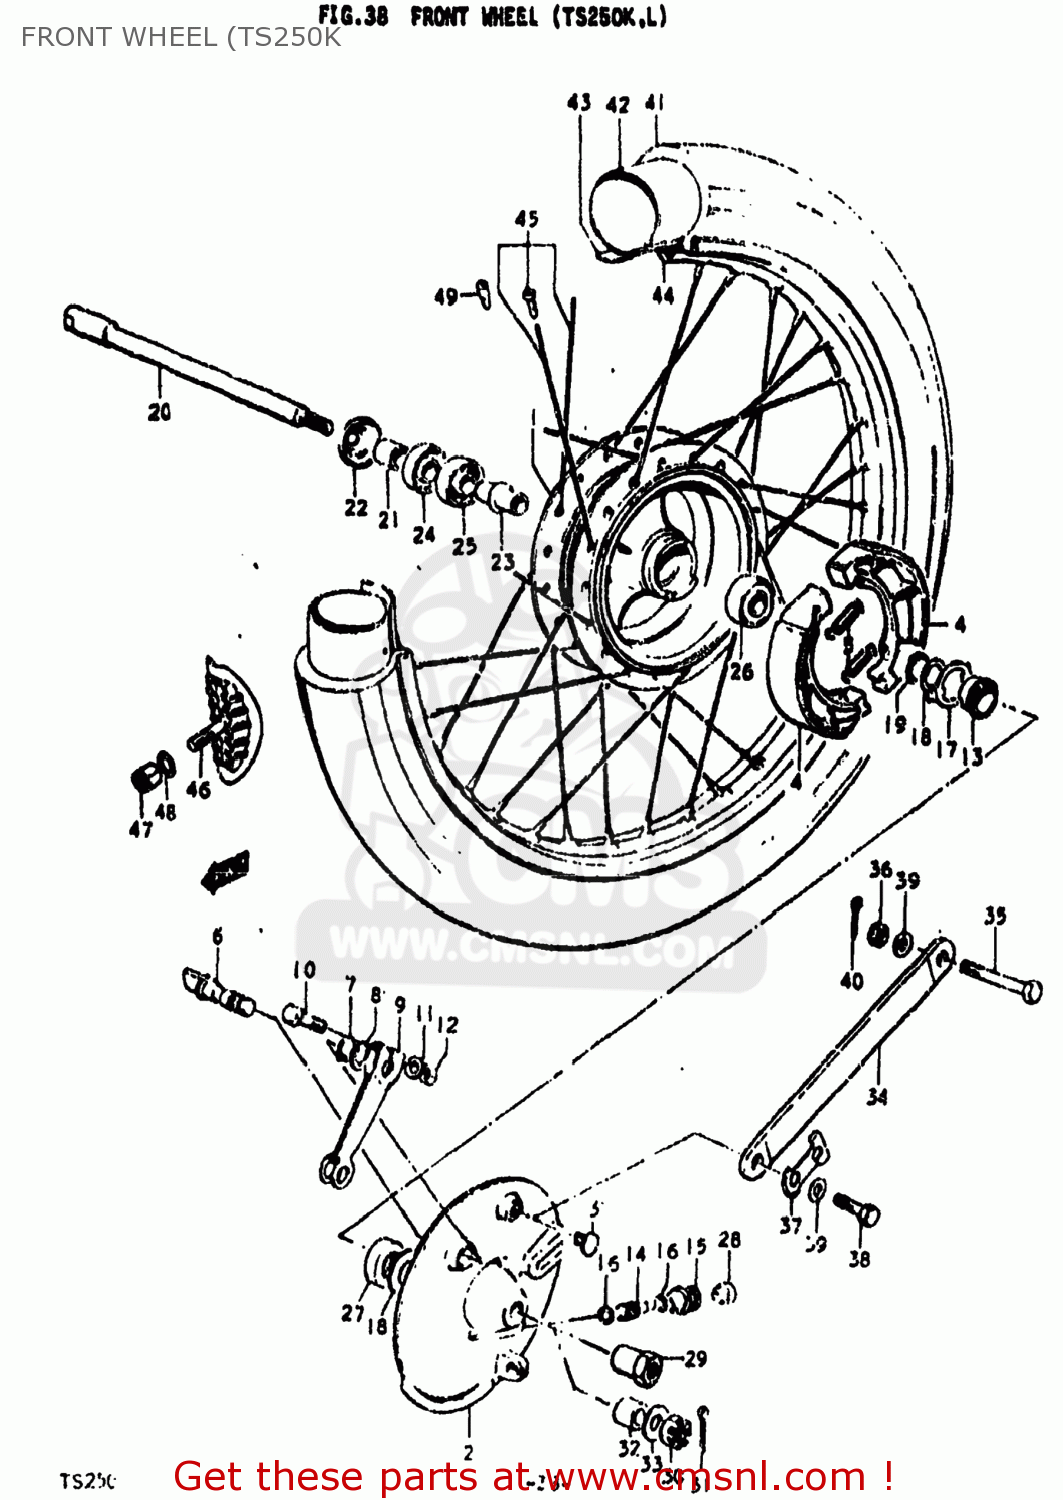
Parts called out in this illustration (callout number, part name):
1	HUB,FRONT
2	PANEL,FRONT HUB
3	CAP(OD:20)
4	SHOE,BRAKE
5	SPRING,BRAKE SHOE
6	CAM,FRONT BRAKE
7	O-RING,BOSS
8	WASHER (15X24X1.6)
9	LEVER,FRONT BRAKE CAM
10	BOLT
11	WASHER
12	NUT
13	GEAR,SPEEDOMETER
14	PINION,SPEEDOMETER
15	BUSHING,SPEEDOMETER PINION
16	WASHER (5.1X9X0.4)
17	DRIVER,SPEEDOMETER GEAR
18	WASHER(22.5X27X1)
19	CIRCLIP
20	AXLE,FRONT
21	SPACER
22	DUST SEAL,FRONT HUB DRUM
23	SPACER,FRONT HUB BEARING
24	OIL SEAL
25	BEARING
26	BEARING
27	OIL SEAL
28	OIL SEAL 4.8x10x4
29	NUT,FRONT AXLE
30	NUT 12MM
31	COTTER PIN
32	SPACER
33	WASHER
35	BOLT
36	NUT 8MM
37	MUD FLAP,FRONT FENDER,LEFT
38	BOLT(8X19.5)
39	WASHER
40	PIN
41	TIRE,FRONT
42	TUBE
43	PROTECTOR,WHEEL,INNER
44	RIM,FRONT WHEEL
45	SPOKE SET,FRONT
46	STOPPER,BEAD
47	NUT
48	NUT
49	BALANCER,WHEEL (50G)
